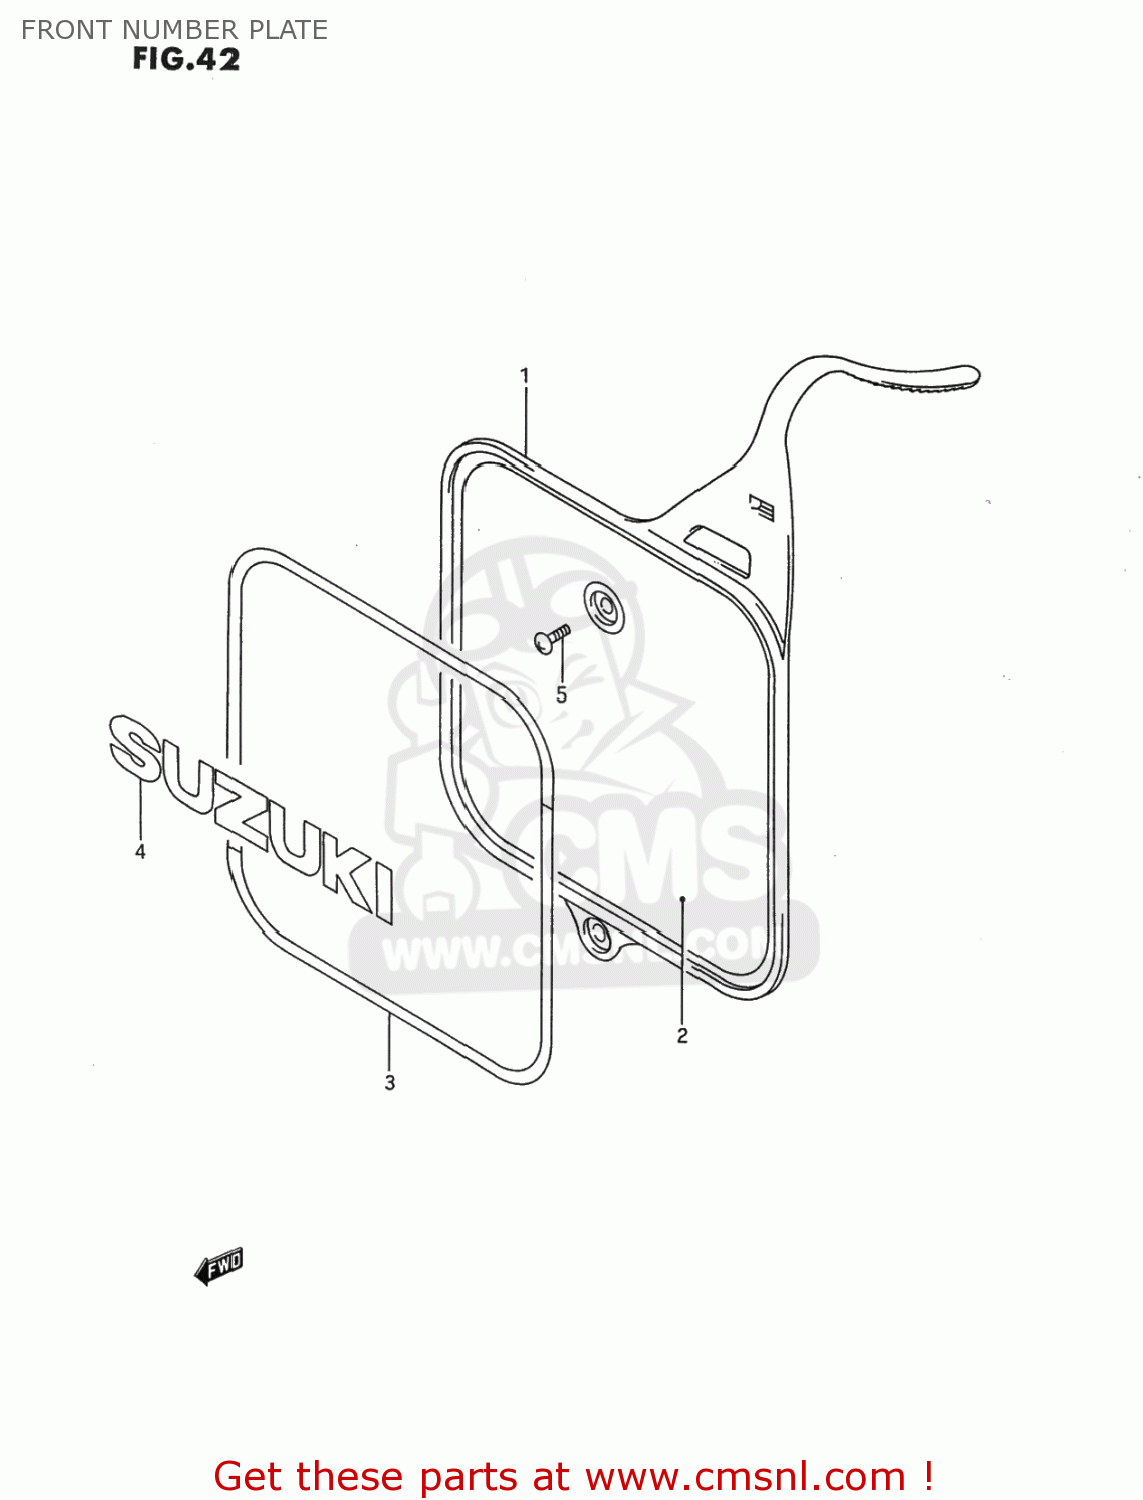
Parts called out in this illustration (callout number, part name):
1	PLATE,NUMBER FR
2	TAPE SET,FRONT NUMBER
3	TAPE SET,FRONT NUMBER
4	EMBLEM,FRONT NUMBER PLATE (SUZUKI)
5	SCREW
